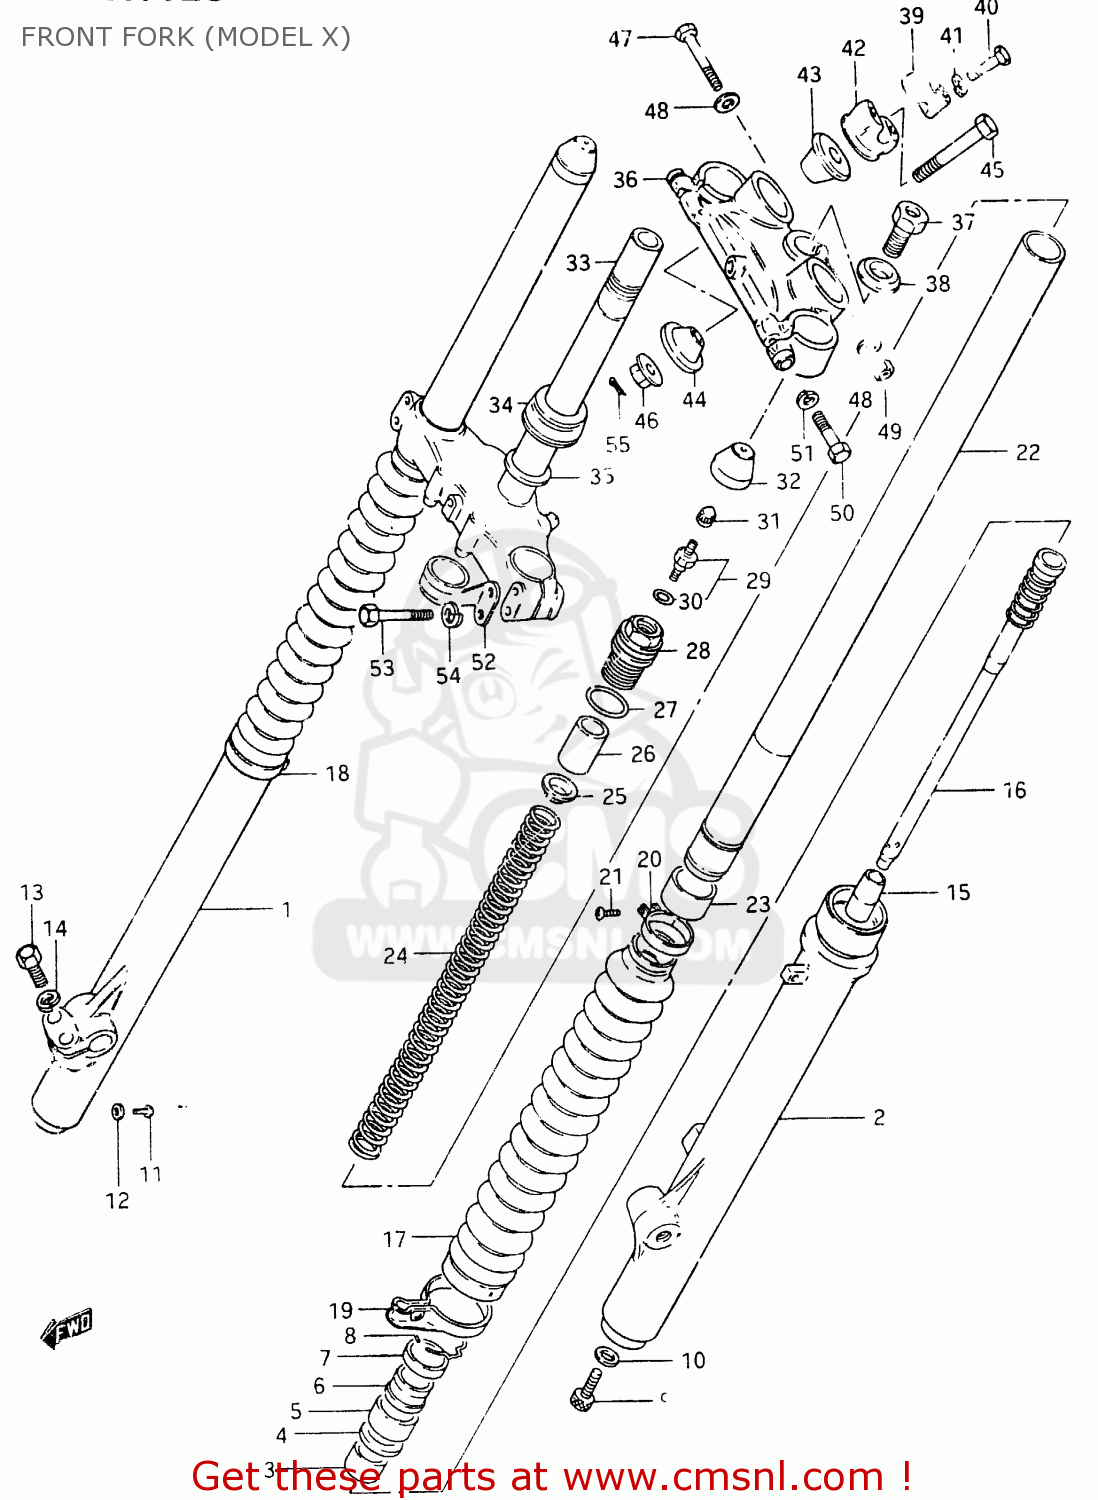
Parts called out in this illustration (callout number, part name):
1	TUBE,OUTER,RIGHT
2	TUBE,OUTER,LEFT
3	METAL,SLIDE
4	WASHER
5	OIL SEAL,FRONT FORK
6	SEAL,DUST
7	CASE,DUST SEAL
8	RING,STOPPER
9	BOLT(14X25)
10	GASKET (NAS)
11	SCREW
12	GASKET,DRAIN,PLUG (NAS)
13	BOLT (8X30)
14	WASHER,LOCK,8.
15	PIECE,OIL LOCK
16	CYLINDER,FRONT FORK
17	BOOT,FRONT FORK COVER
18	BAND,FRONT FORK COVER
19	BAND,FRONT FORK COVER
20	BAND,FRONT FORK BOOT
21	SCREW 4X10
22	TUBE,FORK,INNER
23	PISTON
24	SPRING,FRONT FORK
25	GUIDE,SPRING
26	SPACER,FRONT FORK SPRING
27	O RING
28	CAP,FORK INNER TUBE
29	VALVE,FRONT FORK AIR
30	O-RING
31	CAP,VALVE AIR
32	CAP
33	STEM,STEERING
34	BEARING
35	WASHER,THRUST
36	HEAD,STEERING STEM
37	BOLT
38	WASHER
39	HOLDER,HANDLEBAR
40	BOLT
41	WASHER,LOCK,8.
42	HOLDER,HANDLEBAR
43	DAMPER,UPR
44	DAMPER,LWR
45	BOLT,HANDLE HOLDER
46	NUT
47	BOLT 8X50
48	WASHER
49	NUT
50	BOLT
51	WASHER,LOCK,8.
52	GUIDE,CABLE
53	BOLT 8X40
54	WASHER,LOCK,8.
55	PIN 20X20
